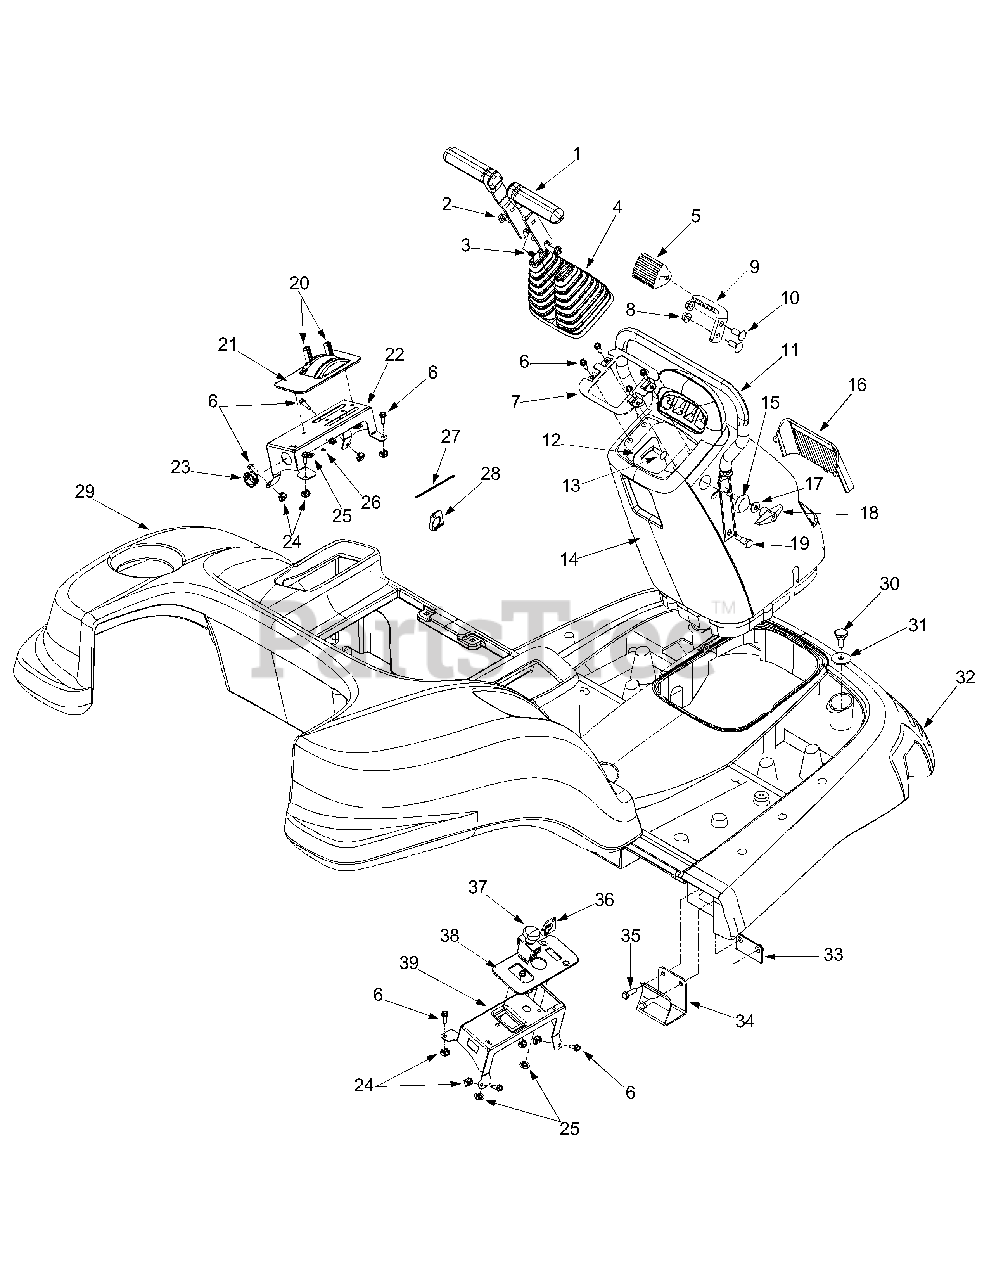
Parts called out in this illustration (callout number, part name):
1	Control Handle
2	Flange Lock Nut 5/16-18
3	Carriage Bolt 5/16-18
6	Hex Washer Screw 1/4-20 x .75
17	Bell Washer .340 ID x .872 OD
18	Wingnut Knob
19	Shoulder Screw
21	LH Control Panel Cover
24	Retainer Nut 1/4-20
25	Push Nut
28	Key
30	Shoulder Screw 3/8-16
31	Flat Washer .406 ID x 1.5 OD
33	Body Plate Assembly
36	Key
37	Electric PTO Switch
38	RH Control Panel Cover
